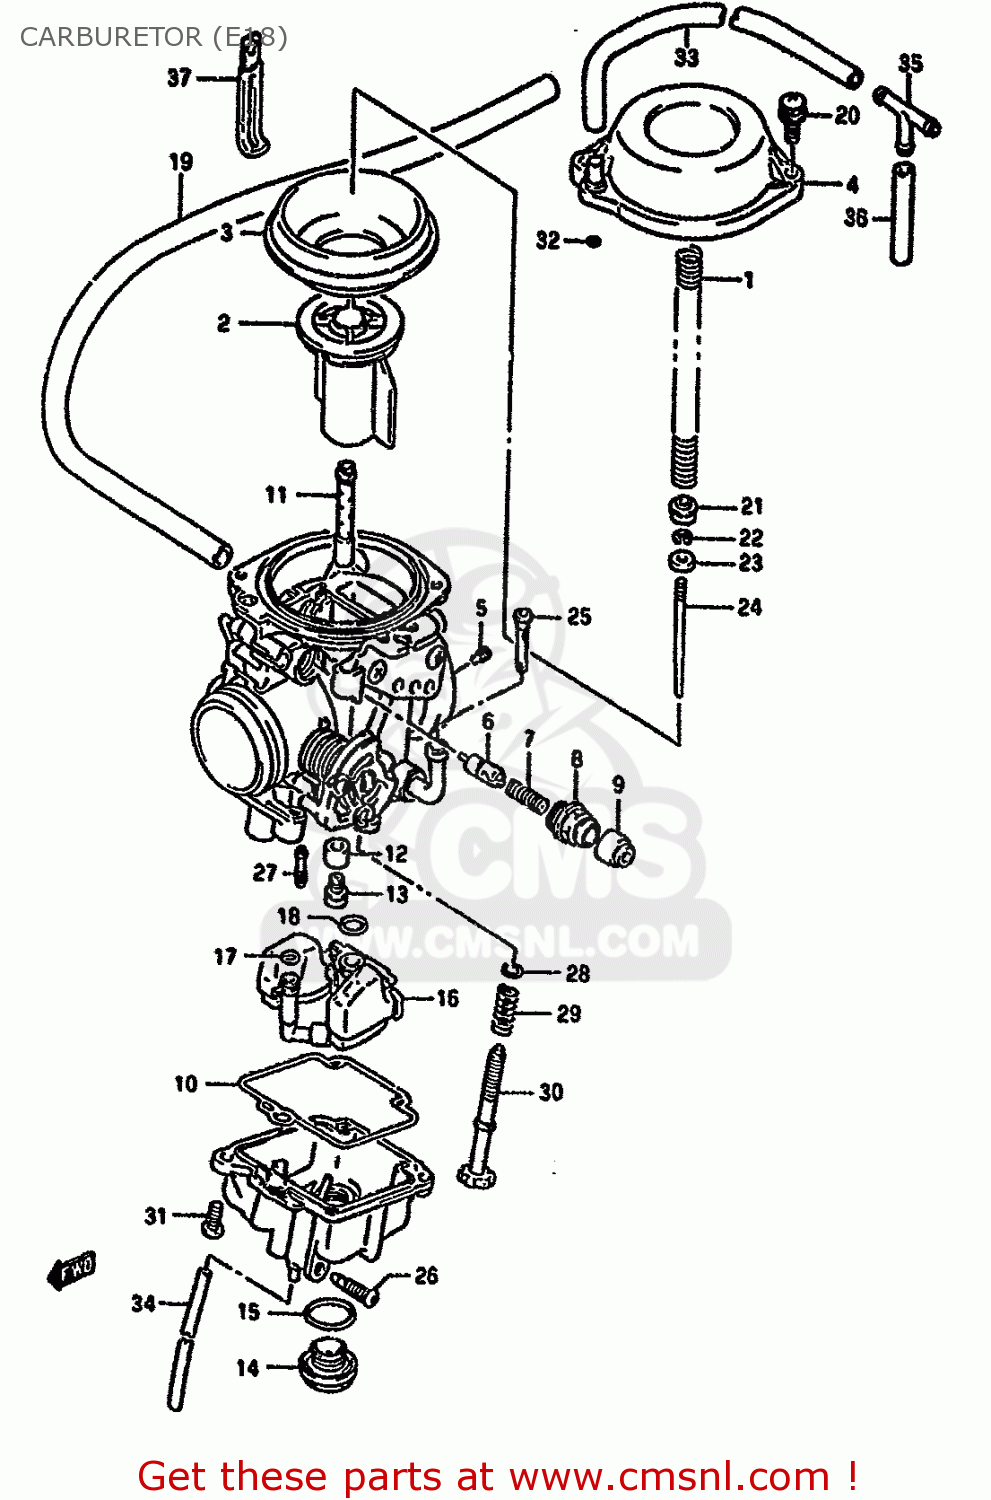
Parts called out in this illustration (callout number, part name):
1	SPRING
2	VALVE,PISTON
3	DIAPHRAGM
4	COVER,DIAPHRAGM
5	JET,AIR
6	PLUNGER
7	SPRING
8	HOLDER,GUIDE
9	CAP
10	GASKET,FLOAT CHAMBER (NAS)
11	JET,NEEDLE(Y-2)
12	RING
13	JET,MAIN(137.5)
14	SCREW,GUIDE
15	O RING,DRAIN PLUG
16	FLOAT/NEEDLE VALVE ASSEMBLY
17	O RING
18	O-RING,NEEDLE VALVE
19	HOSE
20	SCREW
21	RING
22	CLIP,NEEDLE
23	RING
24	NEEDLE,JET
25	FILTER
26	SCREW,DRAIN
27	JET,PILOT(52.5)
28	WASHER
29	SPRING
30	SCREW
31	SCREW
32	O RING
33	HOSE
34	HOSE
35	SCREW,PILOT
36	HOSE
37	CLAMP
38	O RING,PILOT AIR SCREW
39	CLAMP
